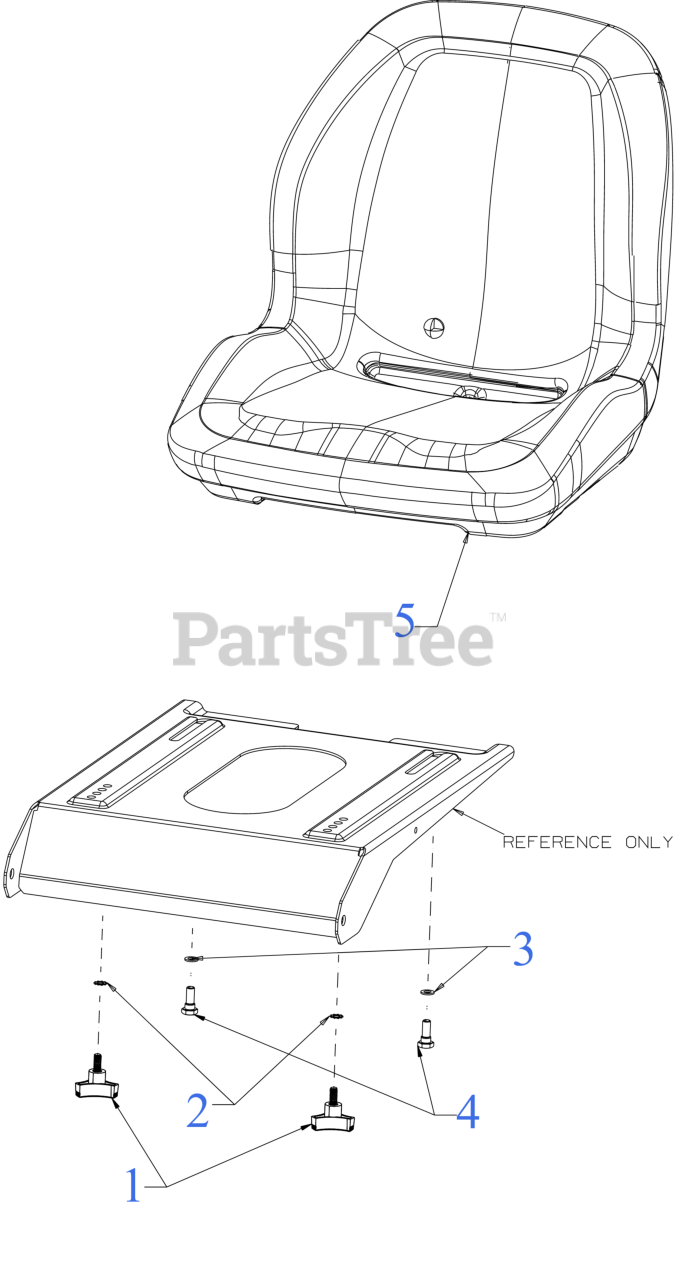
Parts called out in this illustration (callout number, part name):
1	3 PRONG KNOB 5/16-18
3	FLAT WASHER ID-.320 x .598
4	SHOULDER SCREW .437
5	SEAT (TROY/KNB/ADJ)
